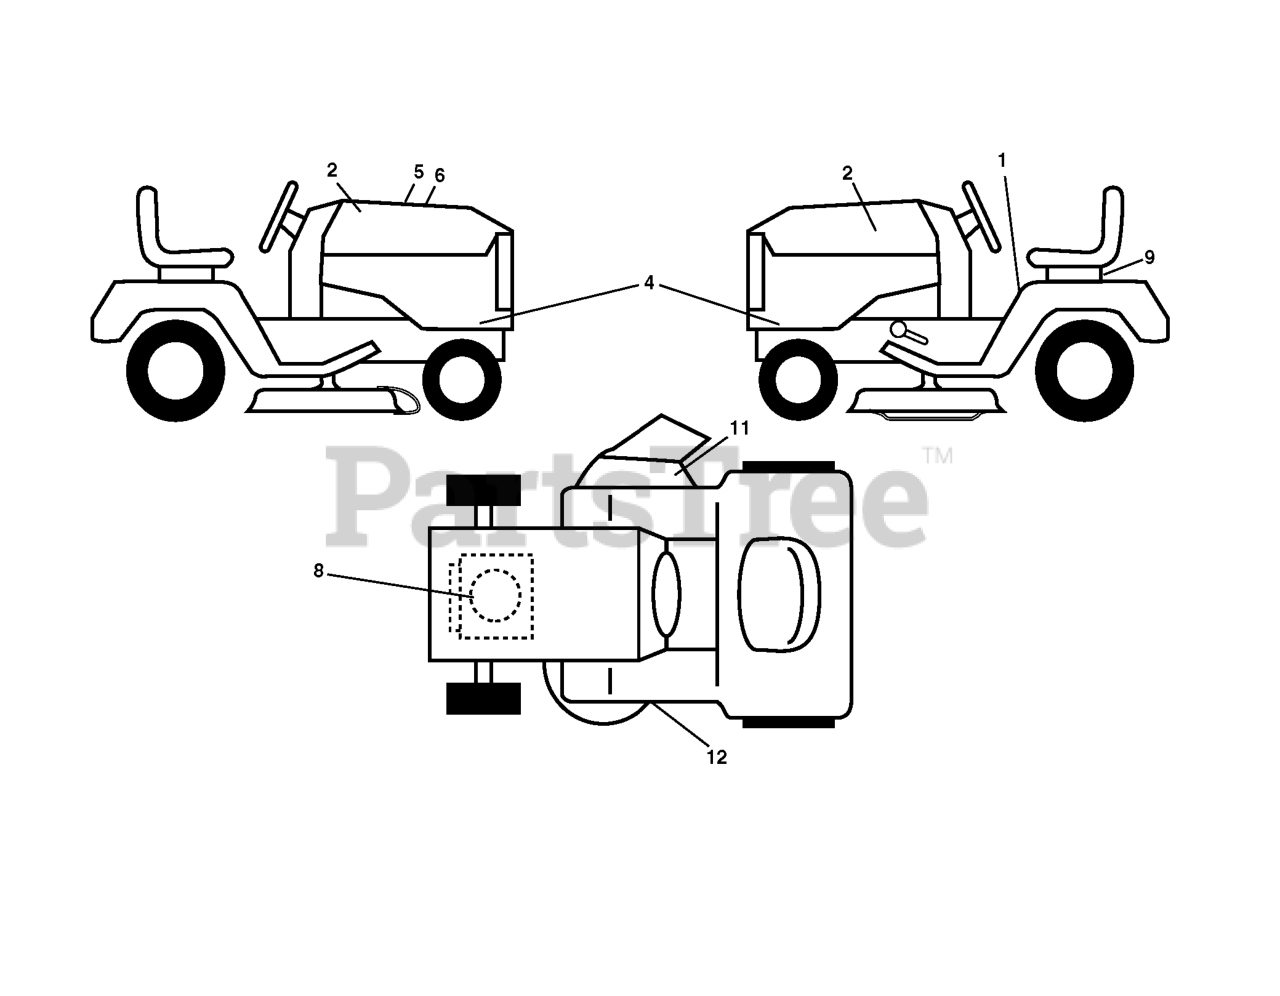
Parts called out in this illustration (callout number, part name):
1	DECAL.FENDER.WARNING.ENG
2	RP.DECAL.BADGE.170MM.TEXTLOGO
4	DECAL PANEL SIDE
5	DECAL.WARNING.CUST.RESP.E85.
6	DECAL.RPL.BSM40.INTK.TLW.42K46
8	DECAL.ENG.BS.20HPXRD.SL.278416
9	DECAL BTRY SYMBOLS
11	DECAL.WARN.KEEP.HAND.AWAY
12	DECAL V BELT SCHEMATIC
